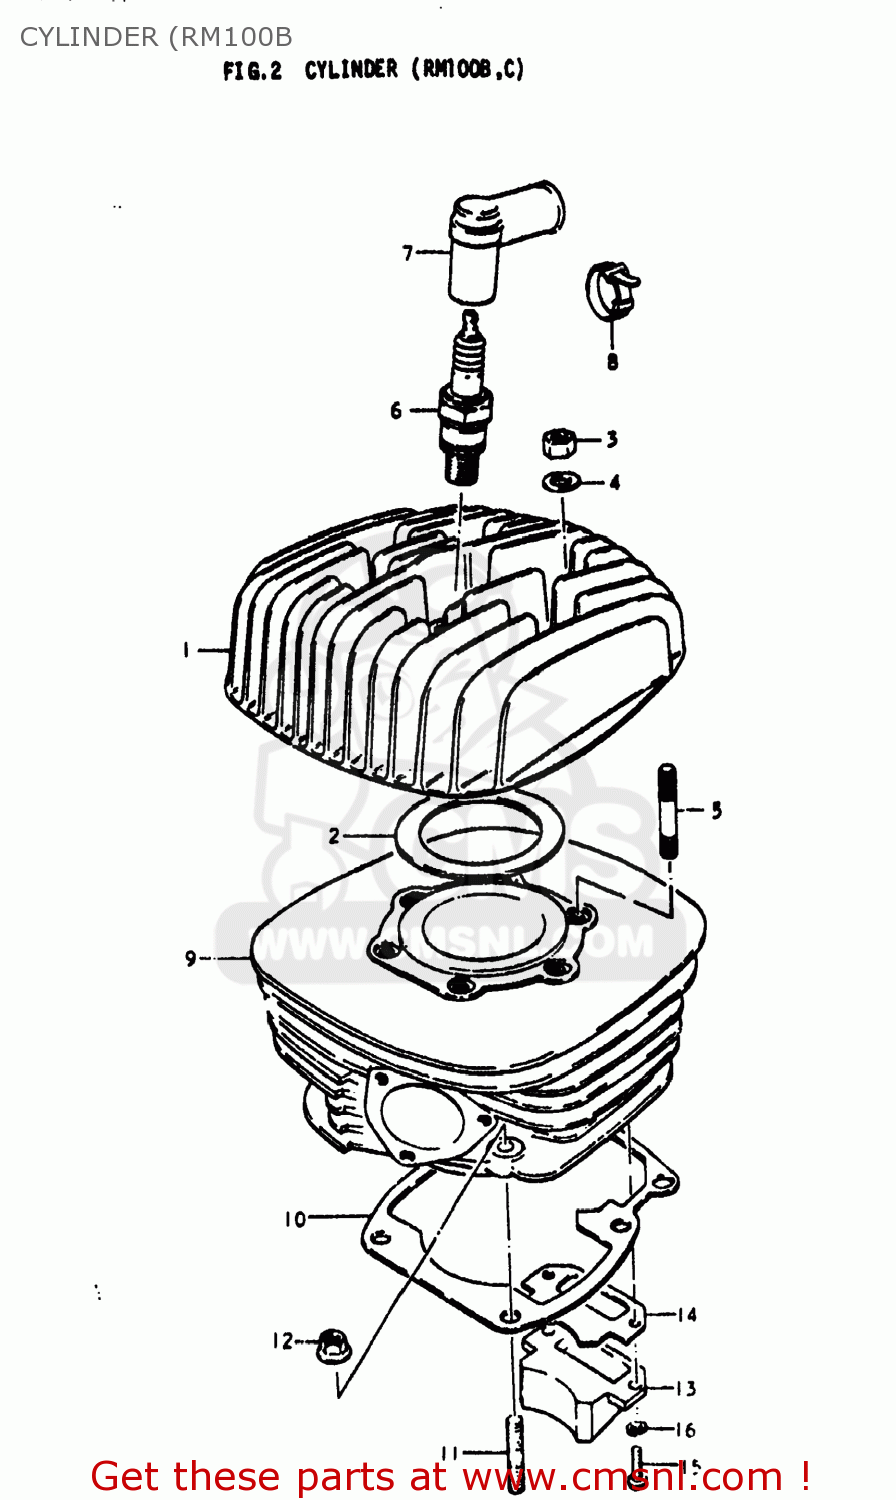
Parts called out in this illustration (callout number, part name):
1	HEAD,CYLINDER
2	GASKET,CYLINDER HEAD (NAS)
3	NUT (8MM)
4	WASHER
5	STUD BOLT
6	SPARK PLUG
7	CAP,SPARK PLUG
8	CLAMP
9	CYLINDER
10	GASKET,CYLINDER (MCA)
11	STUD 8X25
12	NUT
13	VALVE ASSEMBLY,REED
14	GASKET,REED VALVE (MCA)
15	SCREW
16	LOCK WASHER
